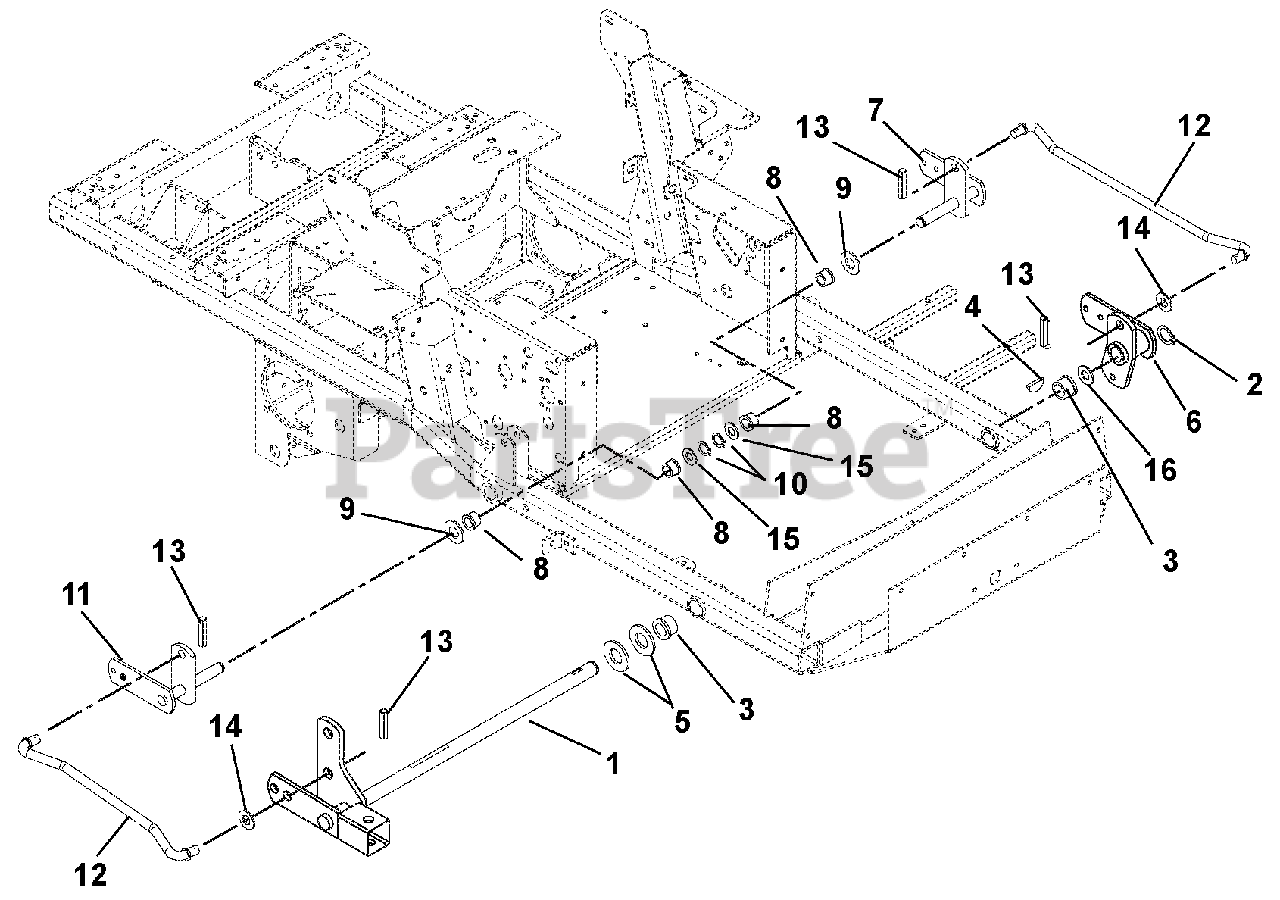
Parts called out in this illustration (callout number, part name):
1	Lift, Mower
2	Ring, Retaining External 1.00 x .078
3	Bushing 1.00 ID x 1.125 OD x 1.50
4	Key, Woodruff .25 x 1.00
5	Bushing 1.00 ID x 1.125 OD x 1.50
6	Weldment, Lift Arm Front
7	Weldment, Rear Lift Arm Left Hand
8	Bushing, Flange Nylon .762 x 1.0 x .58 x 1.48
9	Washer, Hardened Steel .758 x 1.23 x .031
10	Ring, Retaining External .689 x .077
11	Weldment, Rear Lift Arm Right Hand
12	Rod, Lift Assist 19.35"
13	Pin, Roll .25 x 1.25 Stainless Steel
14	Washer, Flat Steel .630 x 1.25 x .062
15	Washer, Flat Steel .812 x 1.50 x .13
16	Washer, Hardened Thrust 1.00 x 1.55 x .03
